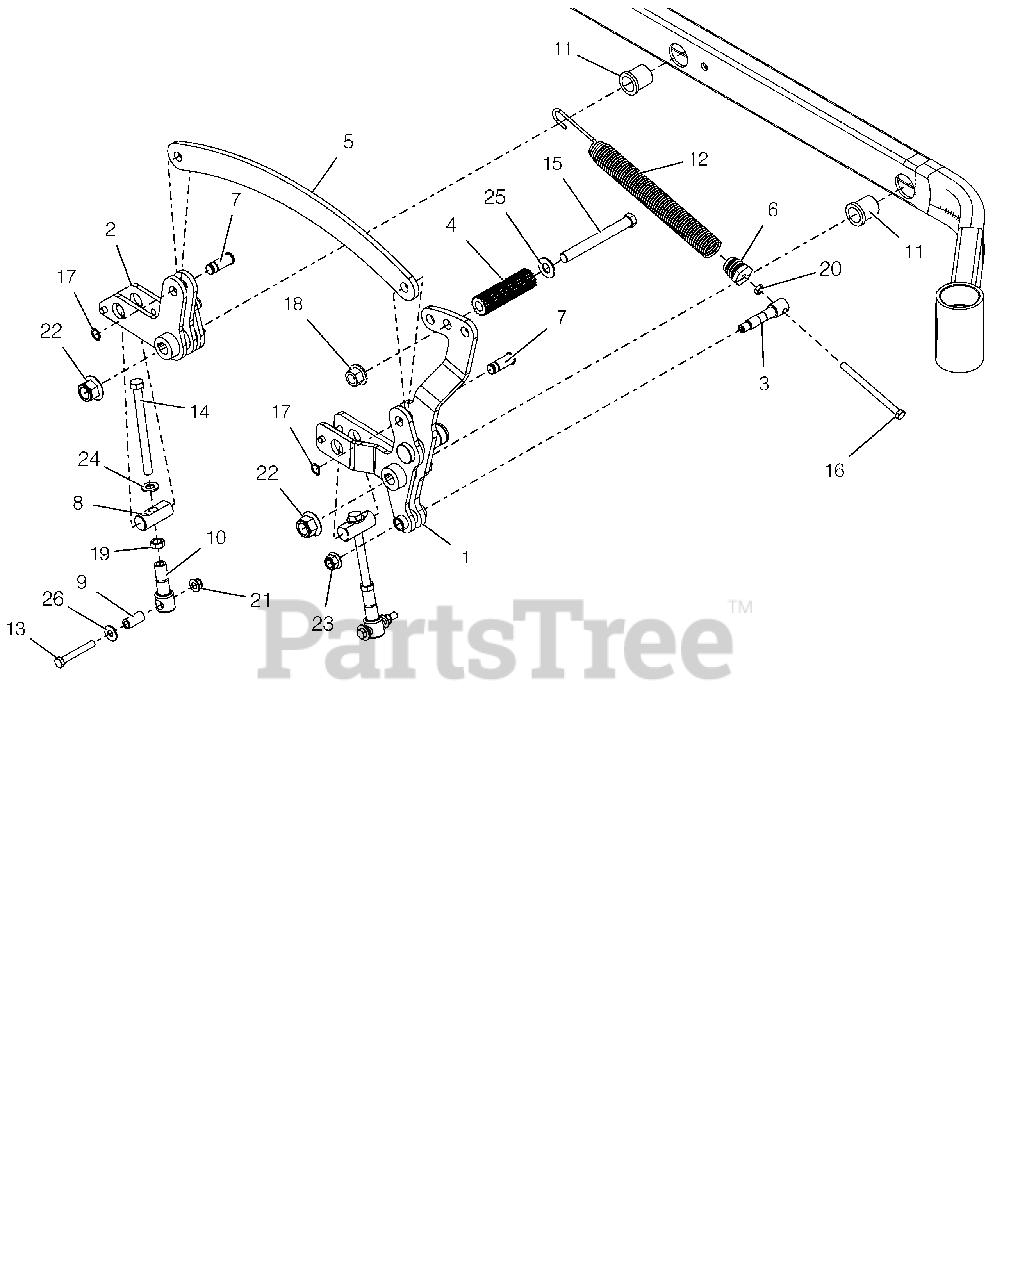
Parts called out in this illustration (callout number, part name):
1	FRONT RH DECK LIFT ARM WMT-LF
2	REAR RH DECK LIFT ARM WLDMT-LF
3	TRUNION, DECK LIFT SPRING
4	ROD, FOOT PEDAL (BLACK)
5	LINK, CONNECTING
6	PLUG, SPRING
7	PIN, CLEVIS .625 SNAP RING
8	PIN, DECK LIFT
9	SPACER, DECK LEVELING
10	LINK, DECK LIFT FORMED
11	BSHG-FLG 1.00X1.25X1.50X1.50
12	SPRING, DECK LIFT
13	BLT-HEX .38-16X2.75 GR8 YWZC
14	BOLT,.50-13X6.00-2.50 LG THD
15	BLT, HEX .62-11X5.50 G5 FBP
16	BLT-HEX .38-16X5.00 GR5 FTH YZ
17	RG-RTNG-EXT .625X.050
18	NUT,FLG-TOP LK .625-11 FBP
19	NUT-JAM .50-13 YWZC
20	NUT-HEX-JAM .375-16 YWZC
21	@NUT-LK-NYL-FLG .38-16 YWZC
22	@NUT-LK-NYL-FLG .75-10 YWZC
23	@NUT-LK-NYL-FLG .50-13 YWZC
24	FLATWASHER 1/2 SAE HARD 15906
25	WSHRFLT 5/8SAE CARBHARD FBP
26	@WSHR-FL-STL.438X1.00X.083 YWZ
